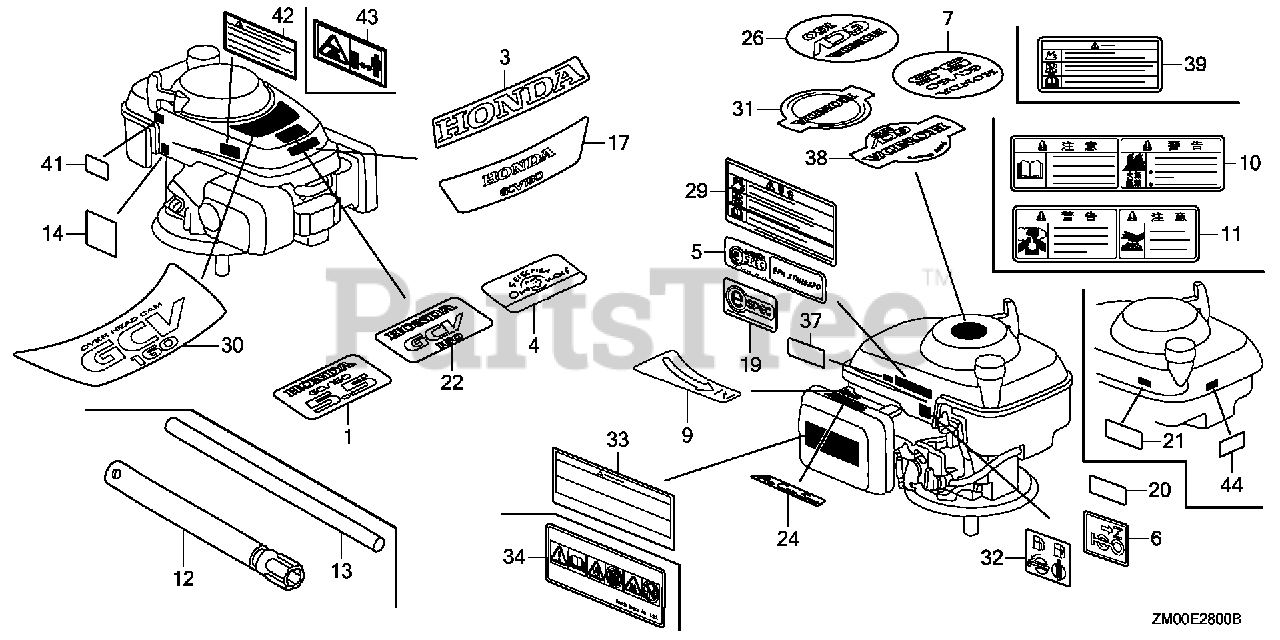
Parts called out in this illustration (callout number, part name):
1	MARK, EMBLEM (GCV160)
9	MARK, CHOKE INDICATION
20	LABEL, WARNING (NOT CERTIFIED FOR SALE)
